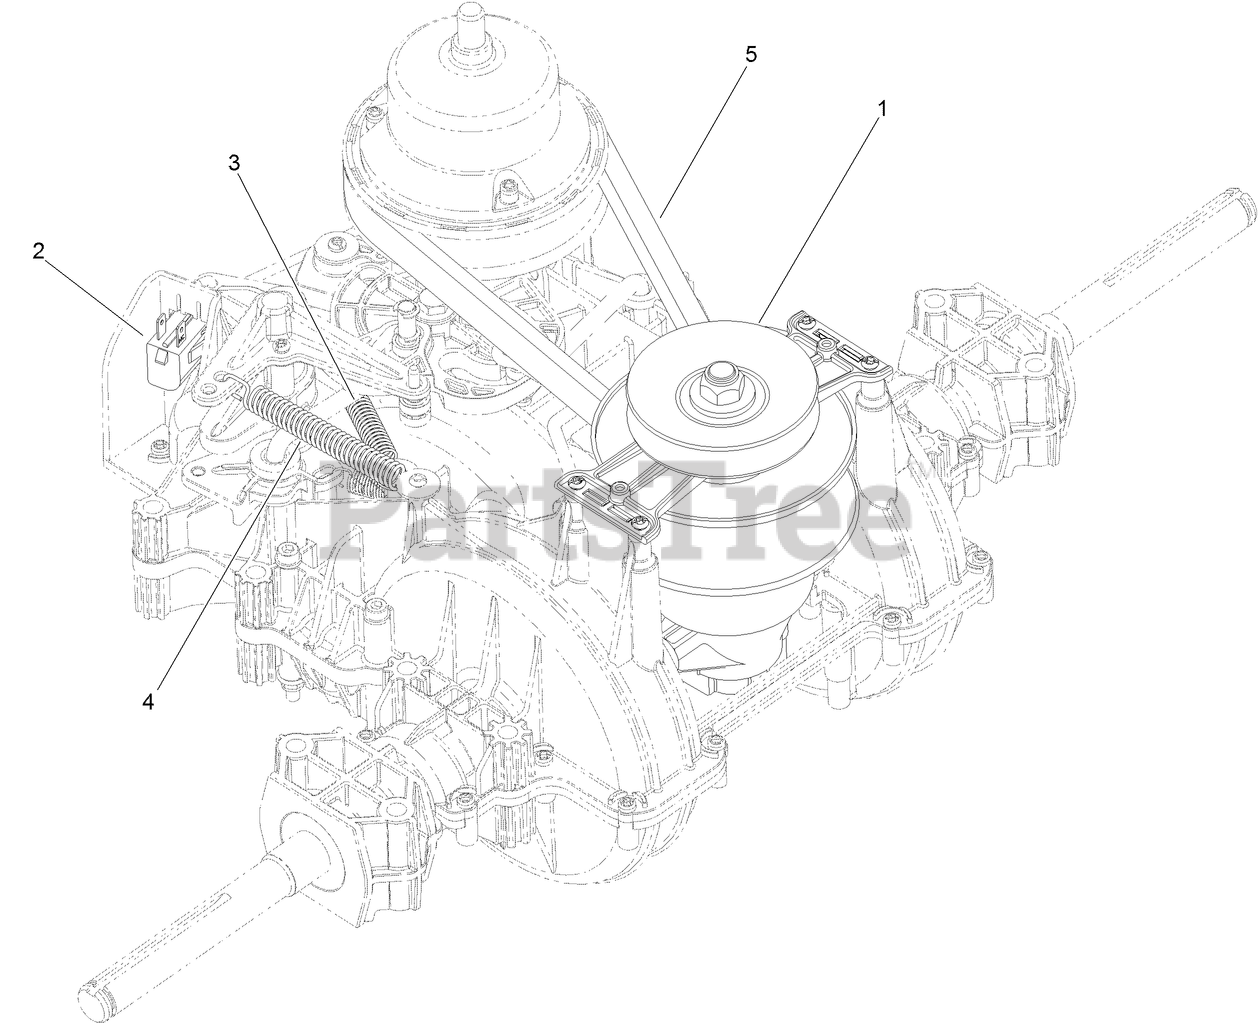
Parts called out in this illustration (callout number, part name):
1	VARIATOR-DRIVE
2	SWITCH-REVERSE
3	SPRING-NEUTRAL
4	SPRING-BRAKE
5	BELT-TRANSMISSION
